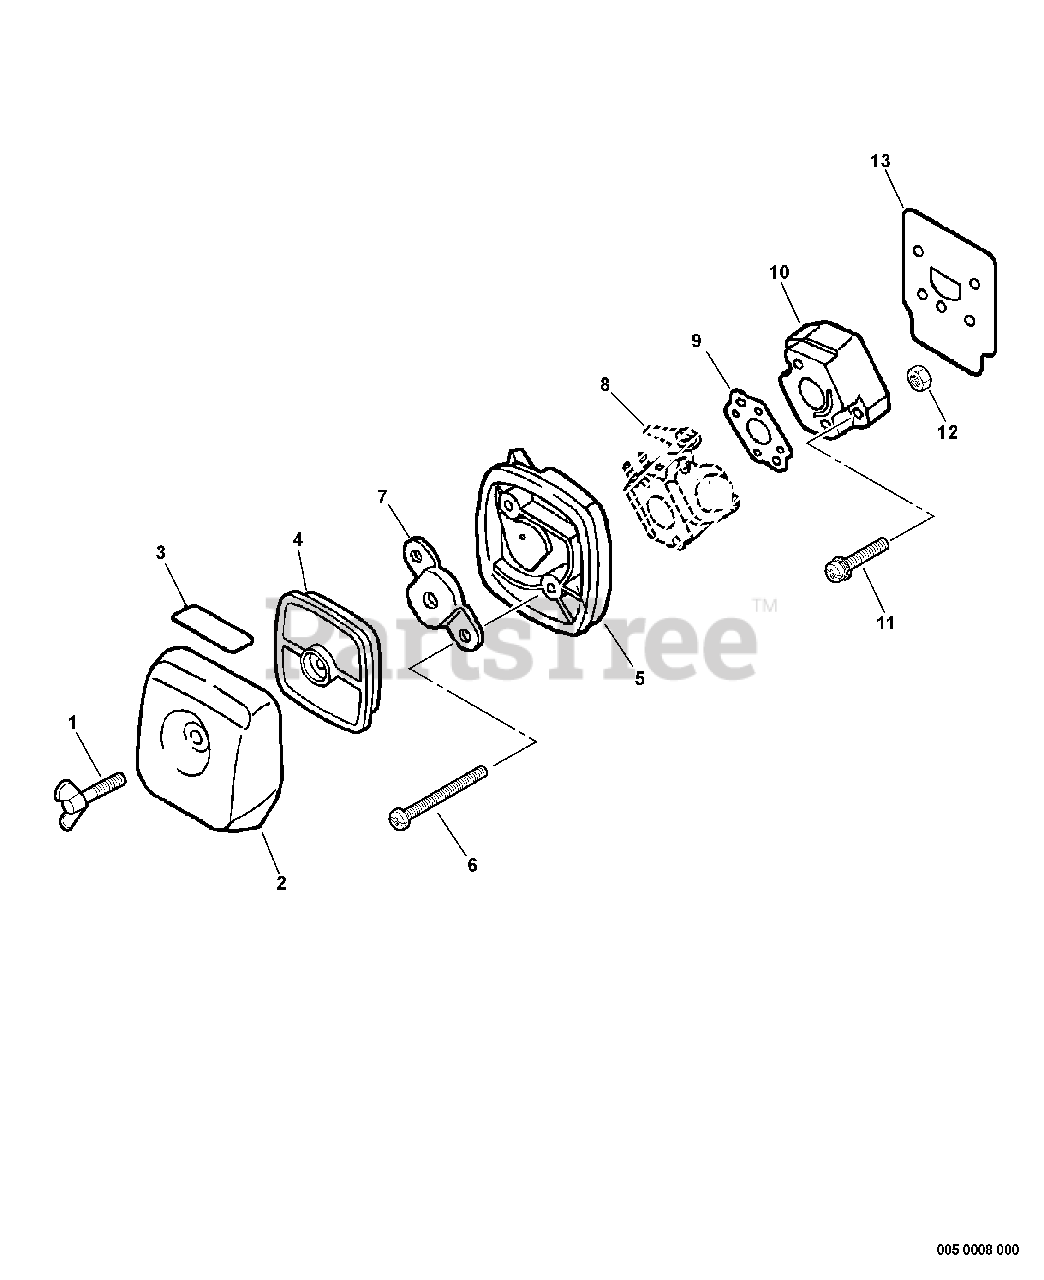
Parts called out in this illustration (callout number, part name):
1	THUMBSCREW
2	COVER, AIR FILTER - GRAY
3	LABEL - CHOKE
4	FILTER, AIR - SINGLE LAYER
5	CASE, AIR FILTER - GRAY
6	SCREW - 5X65
7	PLATE, PREVENT
8	CARBURETOR
9	GASKET, INTAKE
10	INSULATOR, INTAKE
11	SCREW - 5X20
13	SHIELD, INTAKE
